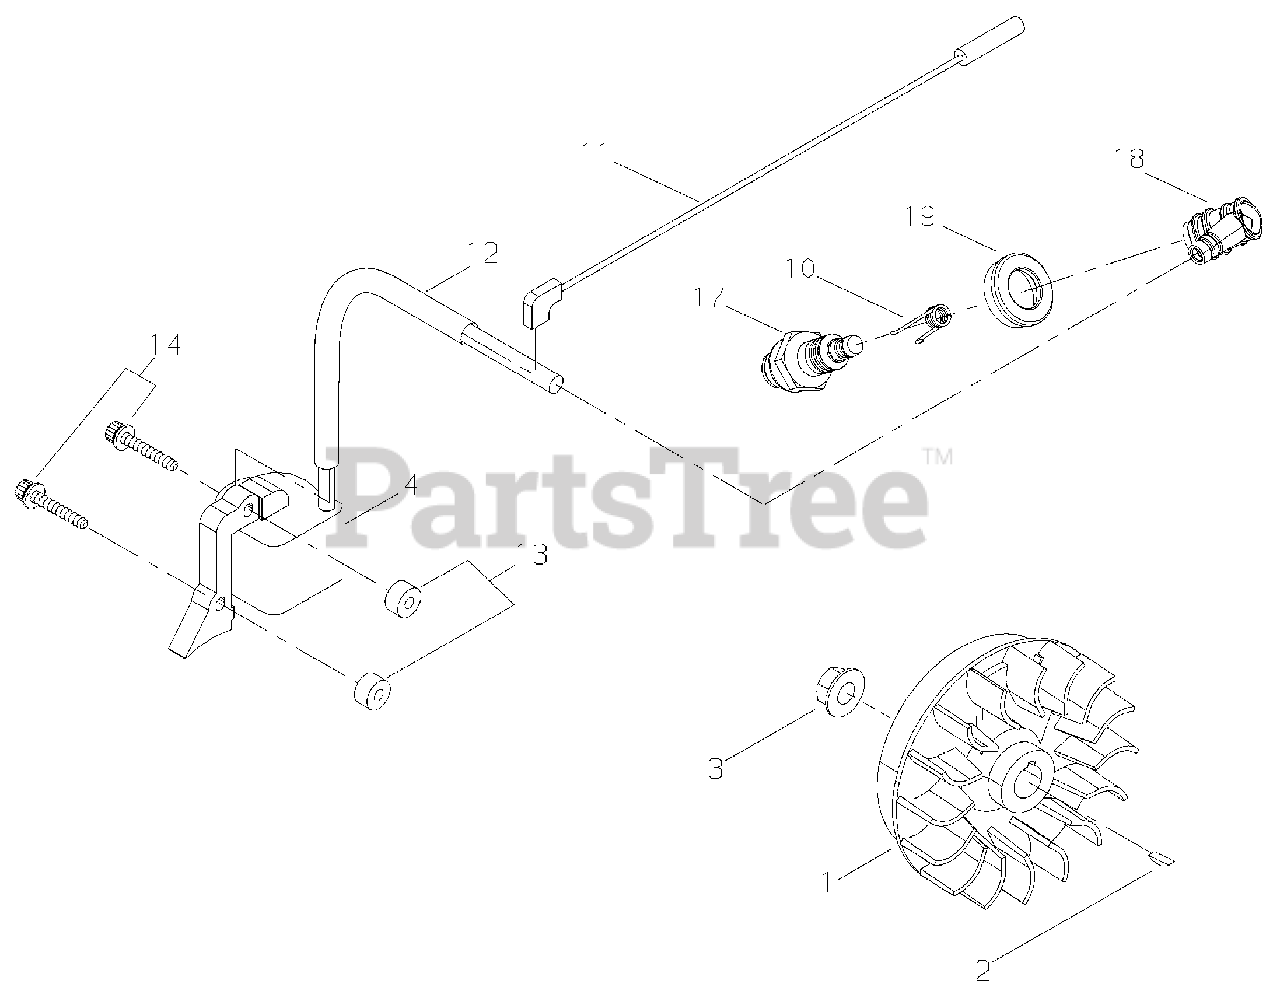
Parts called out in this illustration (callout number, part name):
1	FLYWHEEL
2	KEY, WOODRUFF 3×10
3	NUT M8
4	COIL, IGNITION
10	TERMINAL, SPARK PLUG
11	LEAD - IGNITION L= 215
12	TUBE, IGNITION COIL
13	INSULATOR 4.2×11×6
14	BOLT, ADHESIVE M4×20
17	SPARK PLUG - BPMR6A
18	CAP, SPARK PLUG
19	SEAL, SPARK PLUG
